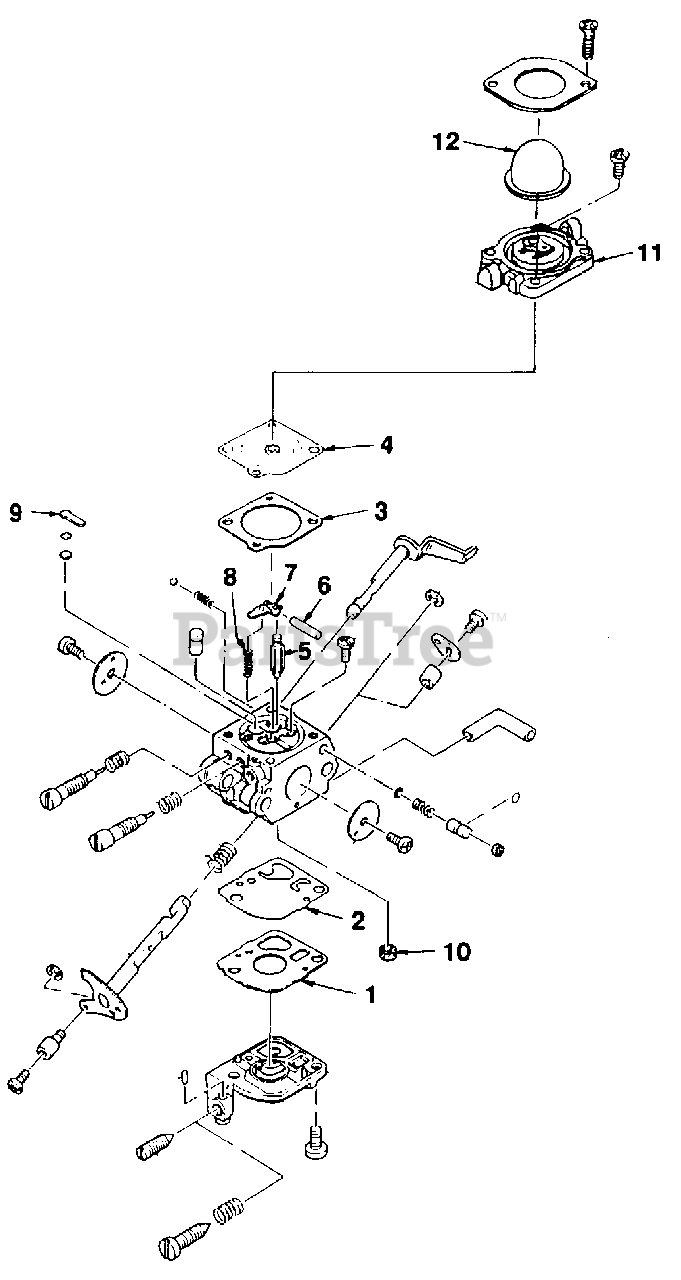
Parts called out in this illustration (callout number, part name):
1	Repair Kit
2	Repair Kit
3	Repair Kit
4	Repair Kit
5	Repair Kit
6	Repair Kit
7	Repair Kit
8	Repair Kit
9	Repair Kit
10	Repair Kit
11	Primer Base
12	Primer Bulb
